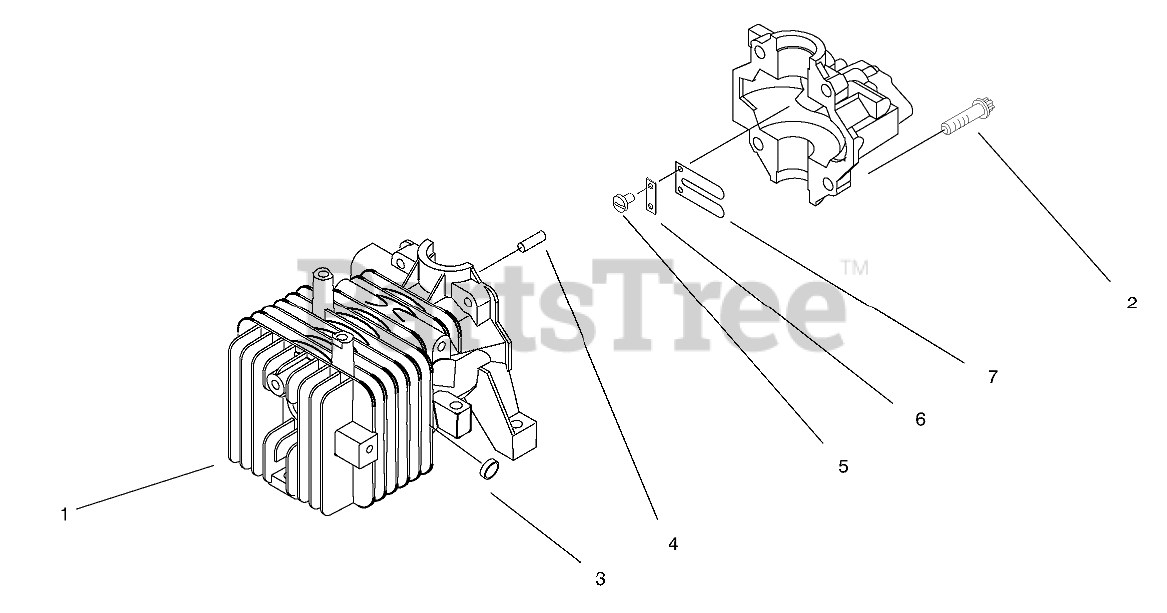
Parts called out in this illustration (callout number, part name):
1	CYL & C/CASE V
2	SCREW-HWH V
3	PLUG-CORE VF
4	DOWEL XEV
5	SCREW-HH
6	PLATE-BACKUP, REED
7	REED-CARBURETOR
